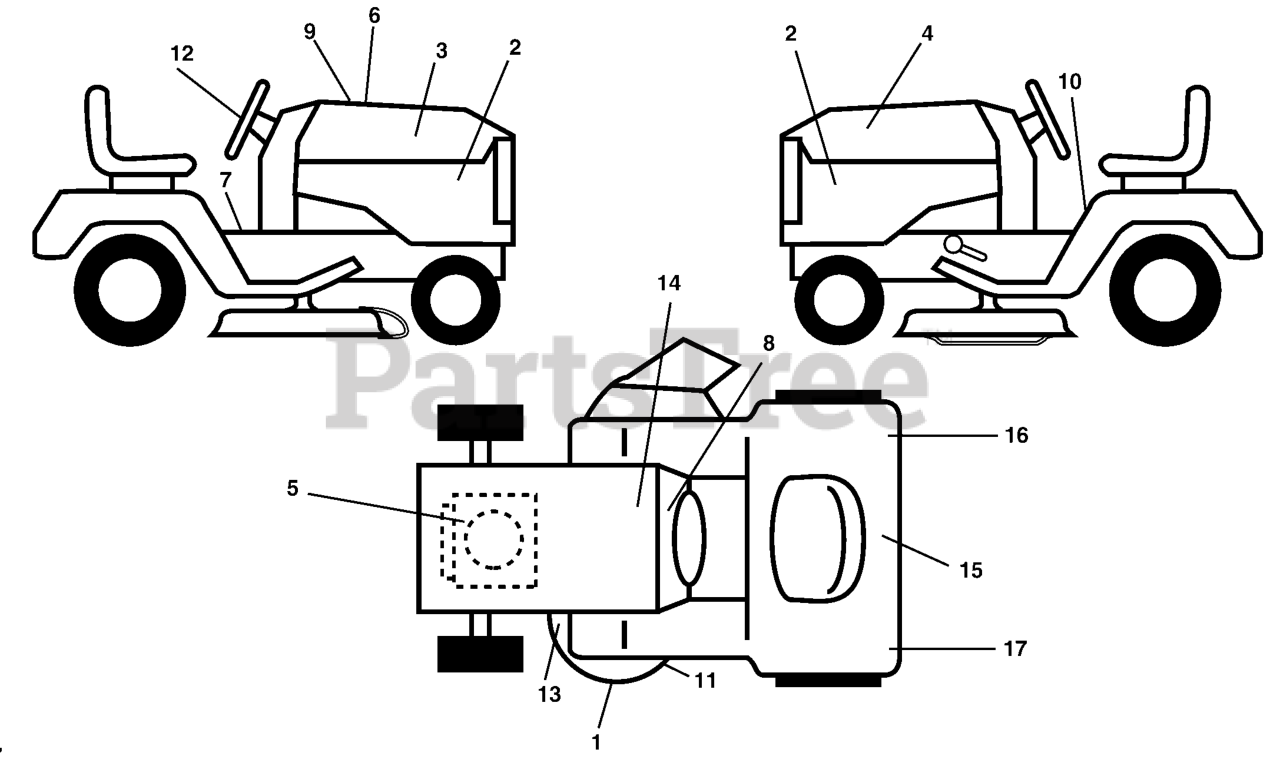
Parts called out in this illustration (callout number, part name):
1	DECAL, MOWER HEAVY DUTY
2	DECAL, PANEL YTH2448
3	DECAL, HOOD RH
4	DECAL, HOOD LH
5	DECAL.ENG.BS.24HP
6	DECAL HOOD CUST. RESP.
7	DECAL.FENDER.HYDRO.ENG
11	DECAL V-BELT SCHEMATIC
12	DECAL.STEERING.HUSQ.BLUE
13	DECAL.MOWER
14	DECAL BTRY SYMBOLS
15	DECAL.FENDER
16	DECAL RH REFLECTOR
17	DECAL REFLECTOR LH
